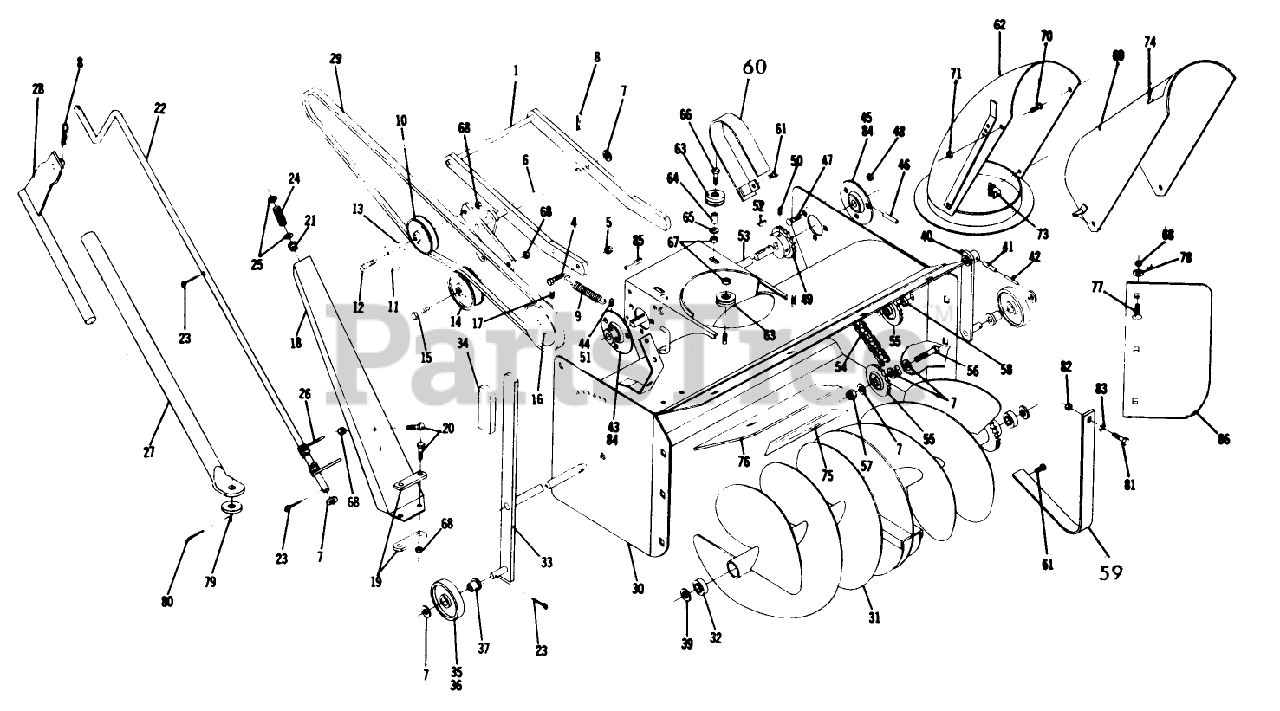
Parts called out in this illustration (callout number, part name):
1	Frame-Mounting
4	Bolt
5	Nut
6	ASSY IDLER ARM R
7	Washer
8	Hairpin
9	SPRING R
10	PULLEY-IDLER
11	Spacer
12	Bolt
13	SPACER
14	Idler Pulley
15	BOLT
16	Pulley
17	Set Screw
18	Crank Support
19	Bar-Reinforcing
20	Bolt
21	NYLINER BUSHING
22	Crank Assembly
23	Pop Rivet
24	SPRING-COMPRESSION
25	Washer
26	CABLE
27	Lift Tube
28	Lid Rod
30	Wrapper Assembly
31	Auger
32	BEARING-BALL
33	Auger Shaft
34	GRIP
35	WHEEL BUSHING ASSY R
36	Wheel
37	Bushing
39	Washer
40	Wheel Support
41	ROLL PIN 1/4 X 1-1/4
42	PIN-SPIROL
43	Ball Bearing
44	Set Screw
45	Ball Bearing
46	PIN-ROLL, SPIROL
47	Bolt
48	Nut
49	SPROCKET
50	SCREW-SET
51	SET SCREW
52	Key
53	Drive Shaft
54	CHAIN
55	Idler Sprocket
56	H H C S
57	Eslok Nut
58	SPACER
59	Guard-Inner
60	Guard-Outer
61	SCREW
62	S/A SHROUD R
63	Roller
64	SPACER
66	Bolt
67	Nut
68	NUT
69	Deflector
70	MACH. SCREW
71	Nut
73	CLAMP
74	Decal-Caution
75	DECAL-WHEEL HORSE
76	Plate-Top Extension
77	Bolt
78	Washer
79	WASHER
80	Cotter Pin
81	H H C S
82	Nut 1/4-20
83	WASHER
84	FLANGE
85	KEY-STRAIGHT
86	Plate
87	H H C S
88	Nut
89	Decal-Safety
